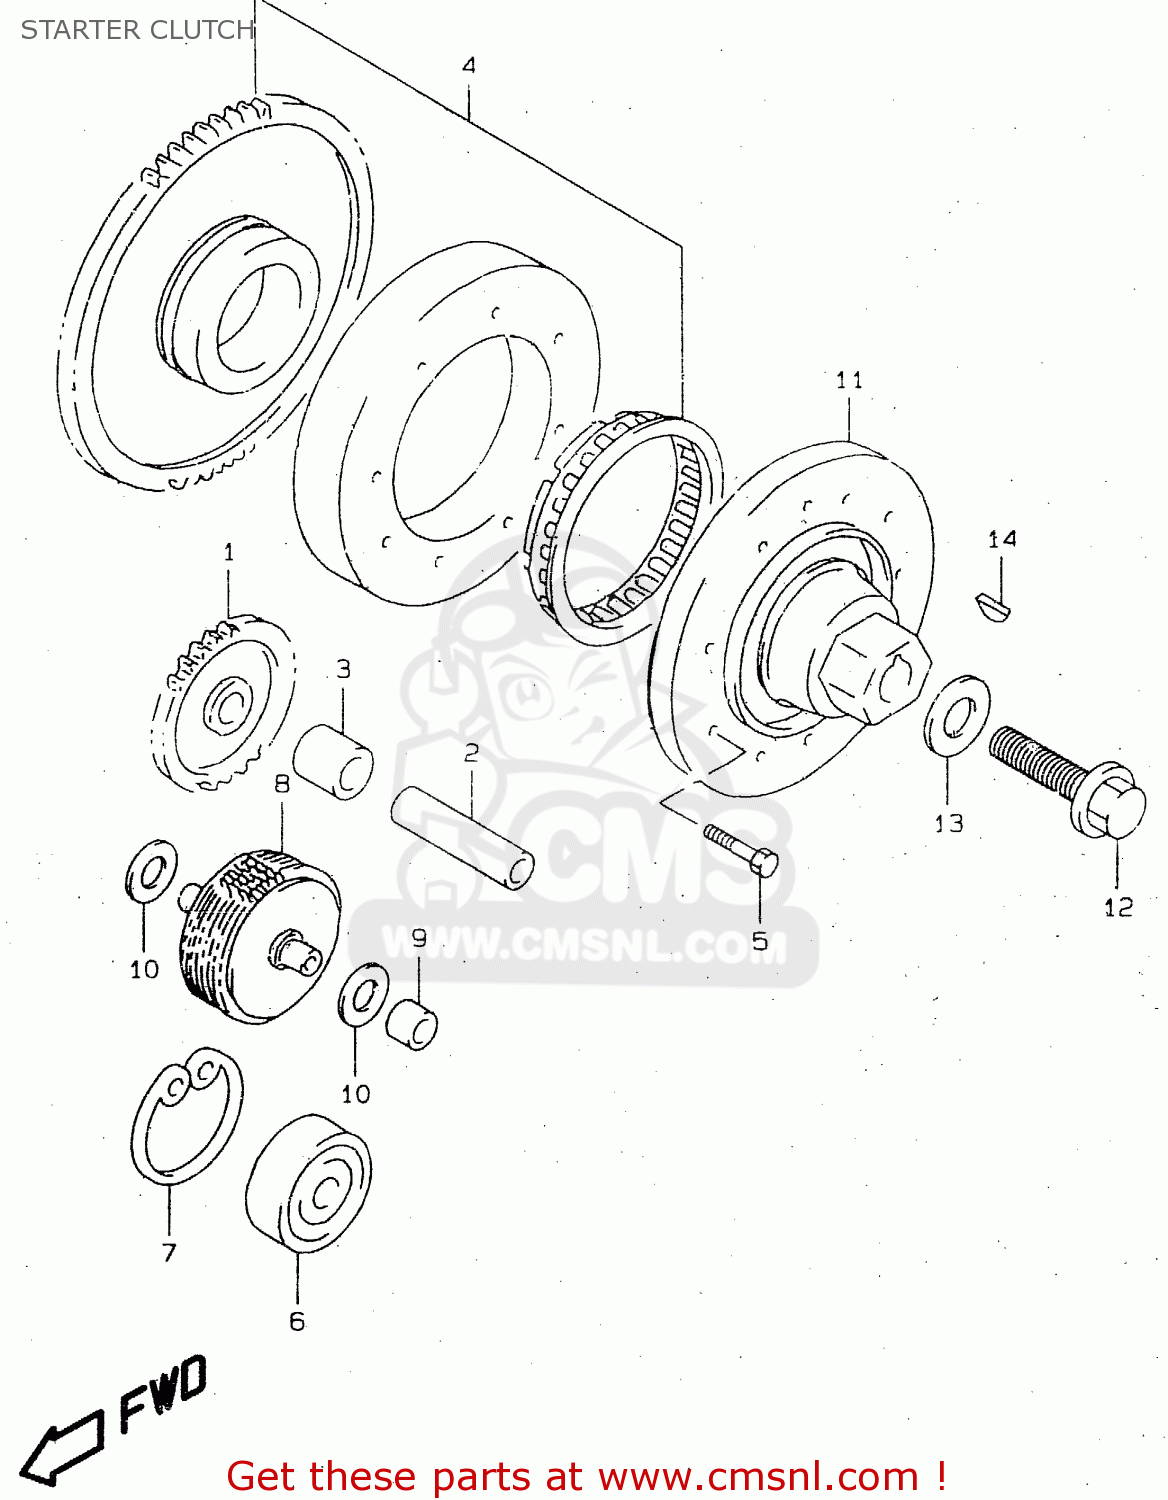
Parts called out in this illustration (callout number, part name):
1	GEAR,STARTER IDLE NO.2
2	PIN(7X12X50.5)
3	SPACER(12.5X19X17.5)
4	CLUTCH SET,STARTER
5	BOLT
6	BEARING(12X28X8)
7	CIRCLIP
8	LIMITER ASSEMBLY,STARTER IDLER GEAR
9	BUSH,LIMITER GEAR SHAFT
10	WASHER
11	HOUSING,STARTER CLUTCH
12	BOLT(12X40)
13	WASHER(12X30X3)
14	KEY
